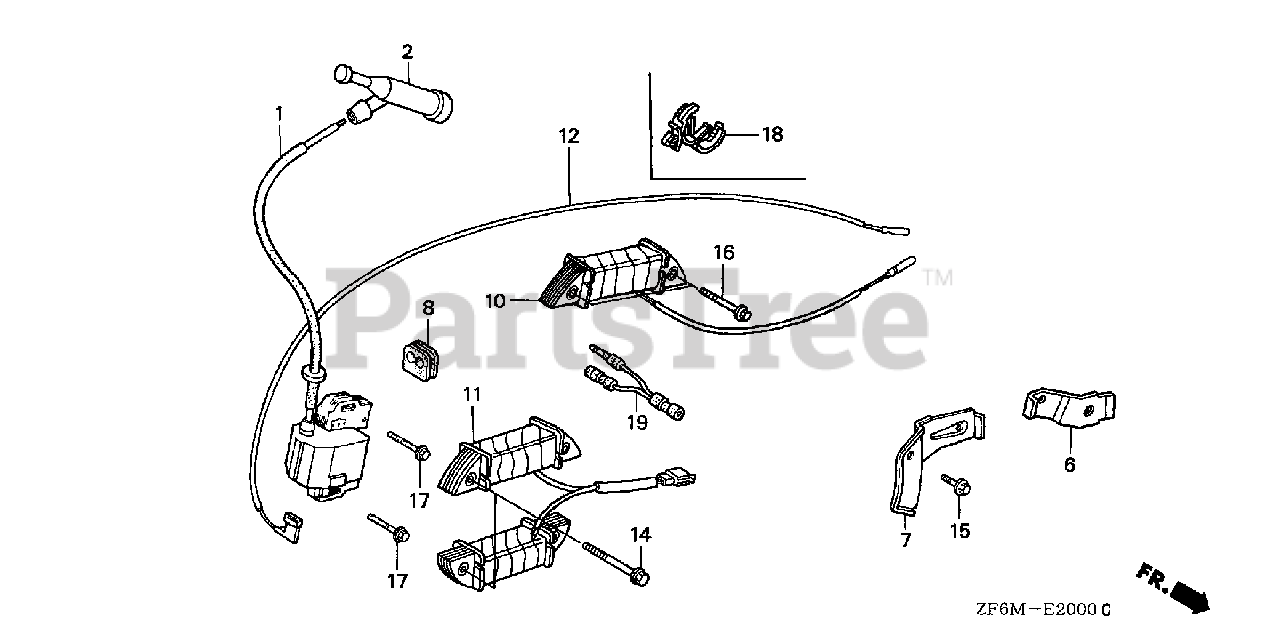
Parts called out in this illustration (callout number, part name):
1	COIL ASSY., IGNITION
2	CAP ASSY., NOISE SUPPRESSOR
8	GROMMET, WIRE
12	WIRE, STOP SWITCH (430MM)
17	BOLT, FLANGE (6X28)
18	CLIP, WIRE HARNESS
